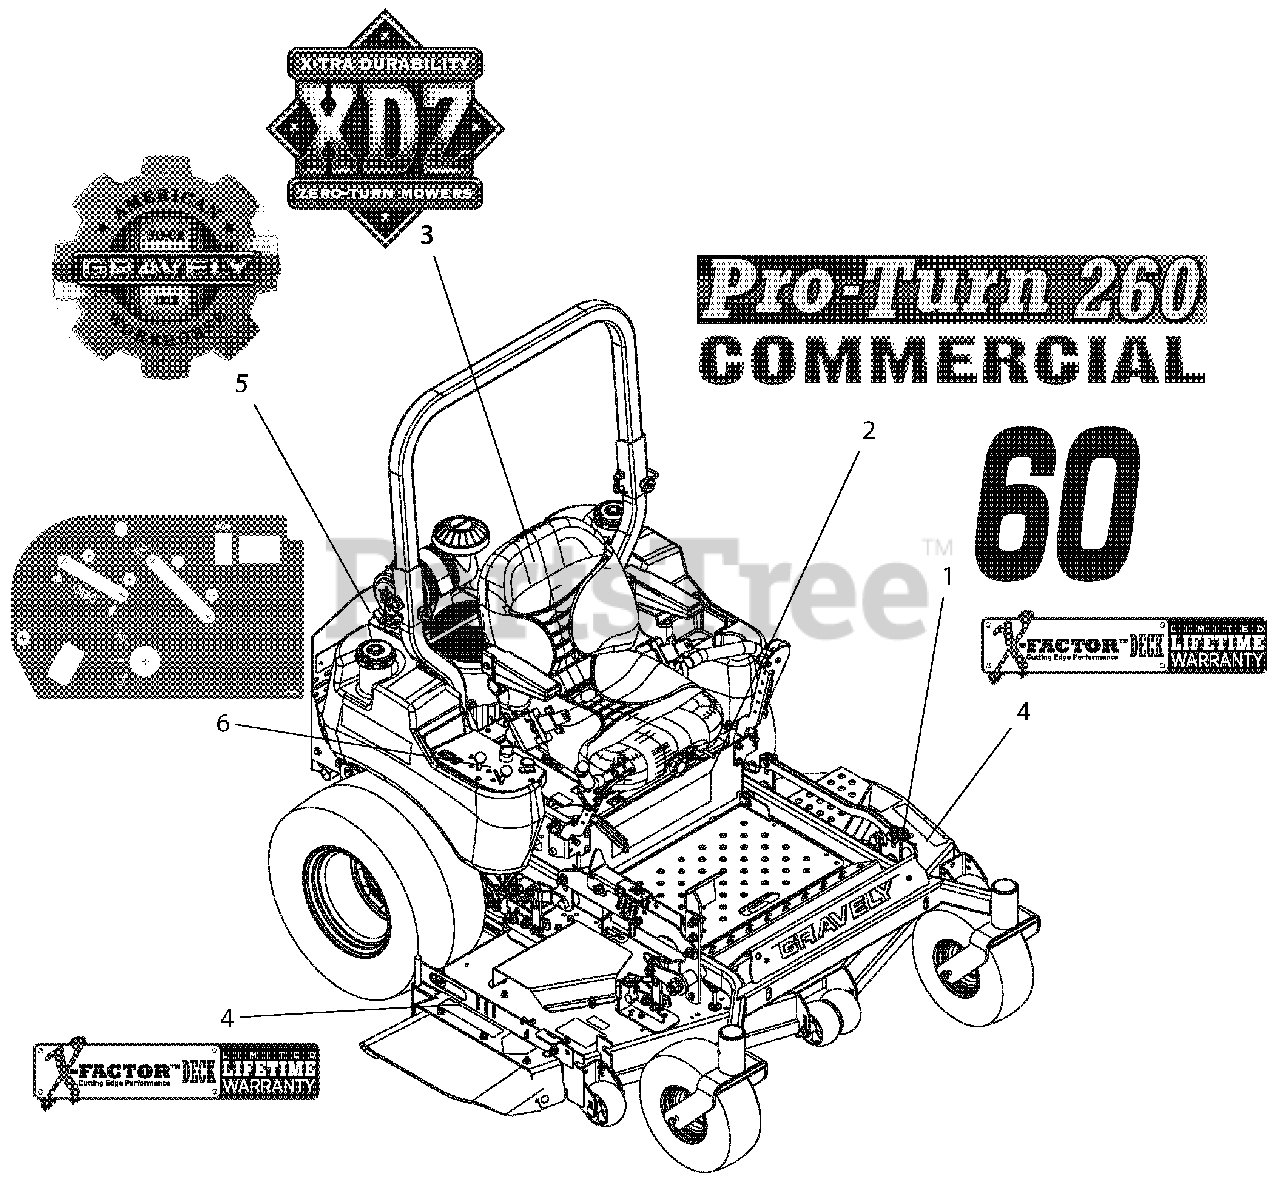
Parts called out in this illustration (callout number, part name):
1	DECAL, 60"
2	DECAL, PROTURN 260
3	DECAL, XDZ
4	DECAL, X-FACTOR DECK
5	DECAL, GRAVELY HERITAGE-LARGE
6	DECAL, CONTROL PANEL NON-EFI
